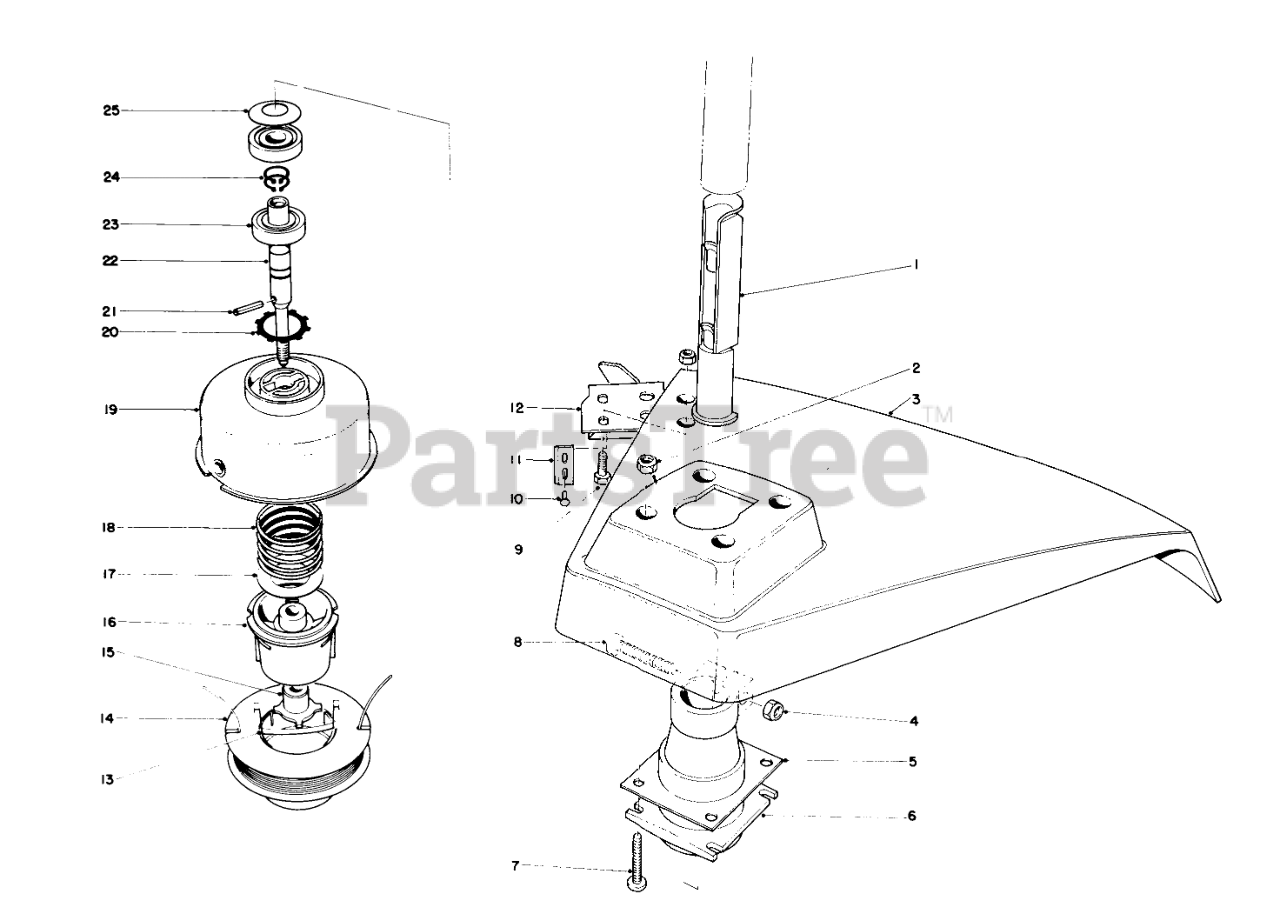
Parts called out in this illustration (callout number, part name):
1	Insert-Pole End
2	NUT-LOCK, NI
3	Shield
5	Gasket-Grass Shield
6	Bearing Housing
7	SCREW-PPH
8	Screw-Pan Head Machine
9	SCREW-HWH
10	RIVET-BLIND
11	Blade-Knife
12	Bracket and Knife Blade Assy. (Incl. Ref. #10 & 11)
13	SADDLE-SPOOL CAP
14	Spool & Line Assembly
15	Driver
16	SPOOL CORE
17	Washer
18	SPRING COMPRESSION
19	Drum & Eyelet Assembly
20	SPRING GRIP
21	COIL PIN
22	POWER SHAFT
23	Bearing
24	RING-SNAP
25	FLAT WASHER
